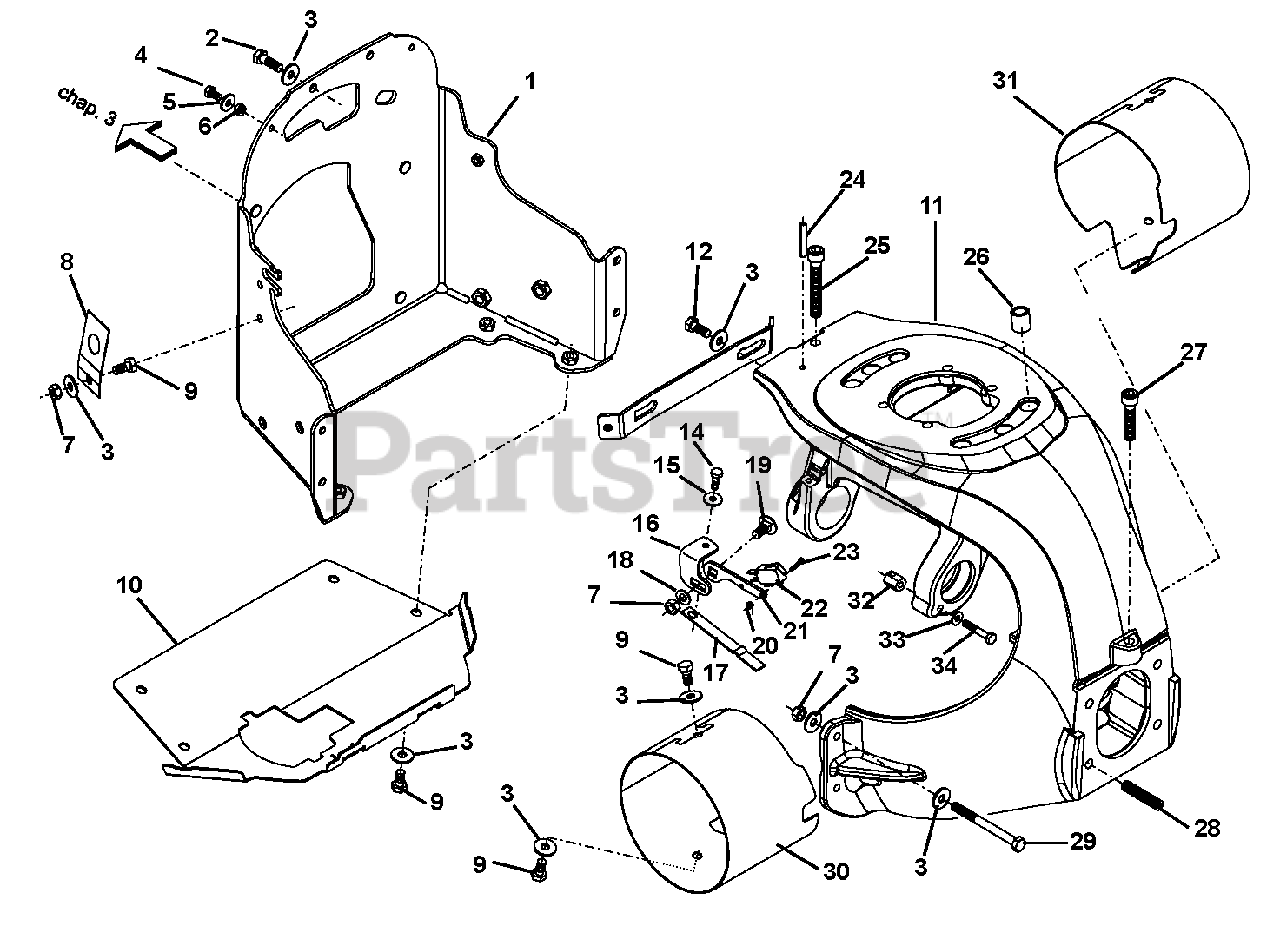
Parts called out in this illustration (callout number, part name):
1	Bracket, Engine
2	Bolt, Hex D933 M8 x 25
3	Washer, M8
4	Bolt, Hex D933 M6 x 12
5	Washer, D9021 6.3 x 18
6	Nut, Lock D985 M6
7	Bolt, Hex D933 M8 x 16
8	Spring, Flat
9	Bolt, Hex D933 M8 x 16
12	Bolt, Hex D933 M8 x 20
14	Bolt, Hex D933 M6 x 18
15	Washer, M6
17	Lever, Spring
18	Washer, M8
19	Truss Head Screw, D603 M8 x 20
20	Nut, Lock D985 M3
21	Plate, Lock
22	Switch
23	Screw, Flat head D85A M3 x 18
24	Pin, Heavy 6 x 40
25	Screw, D912 M10 x 70
26	Collar Sleeve
27	Screw, D912 M10 x 45
28	Screw, Set D913 M10 x 50
29	Bolt, Hex D931 M8 x 90
30	Guard, Grass Right Hand
31	Guard, Grass Left Hand
32	Support, Cable
33	Spacer, 1.03 x 1.38 x .184
34	Screw, D933 Metric 6 x 35
